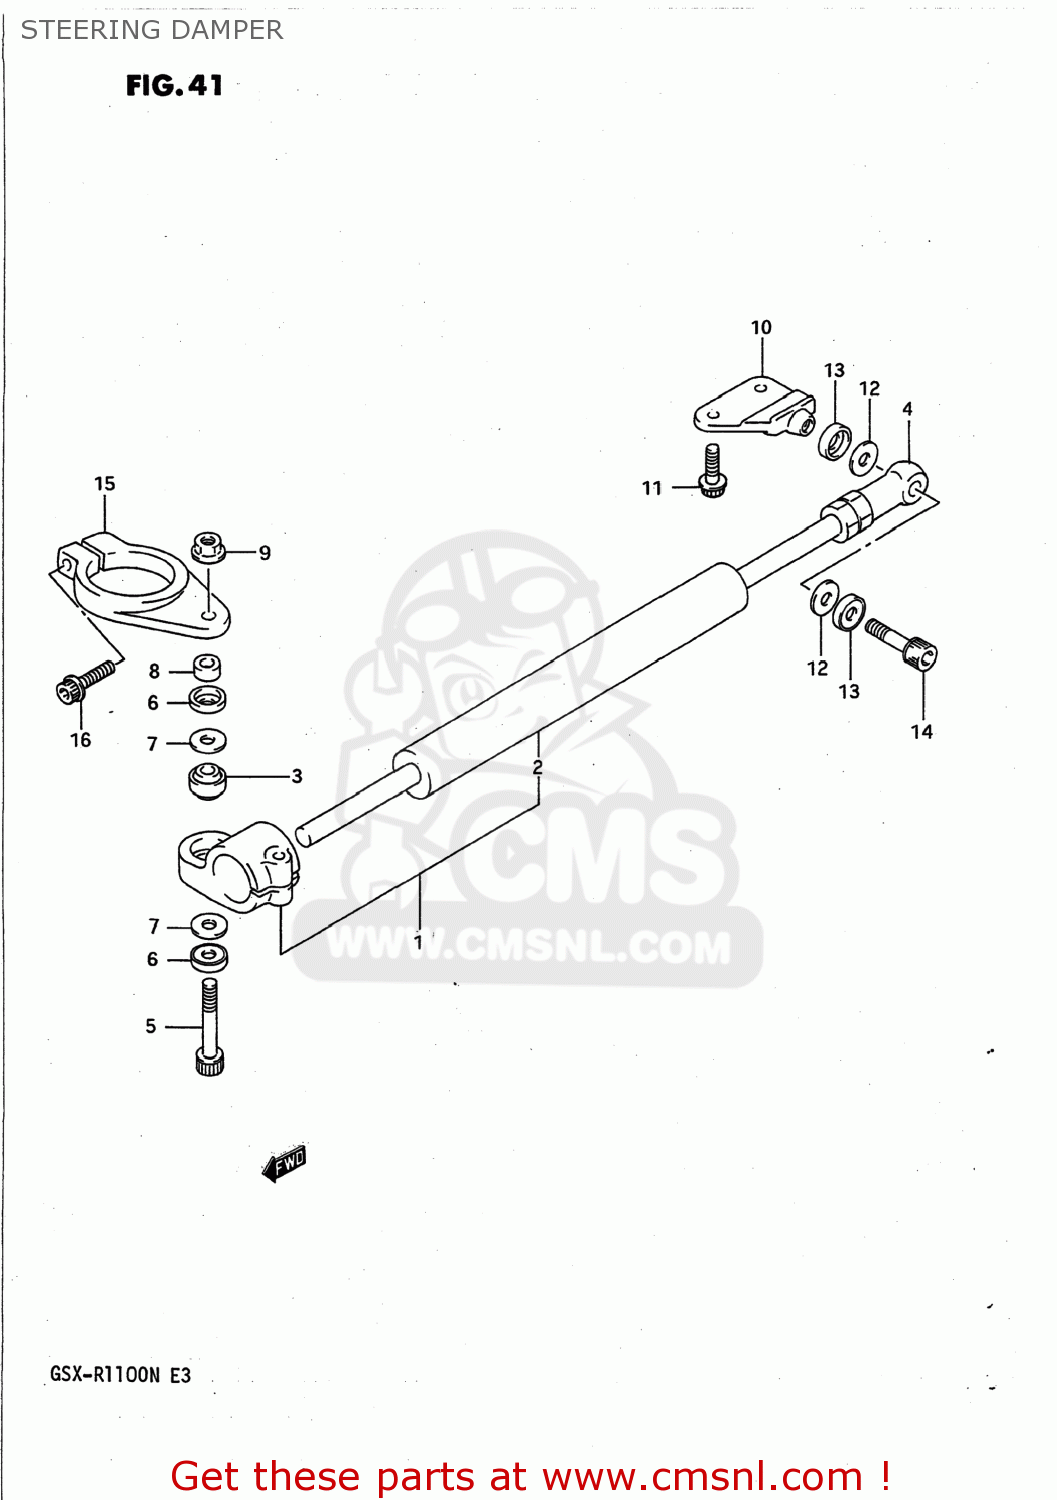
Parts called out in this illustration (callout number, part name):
1	DAMPER ASSEMBLY,STEERING
2	DAMPER,STEERING
3	BEARING(8X17.5X11)
4	PILLOW BALL,ROD END
5	BOLT
6	7
7	SHIM
8	SPACER (8.4X14X6)
9	NUT
10	BOSS,STEERING DAMPER
11	BOLT
12	SHIM
13	14
14	BOLT, FRONT RH
15	BRACKET,STEERING DAMPER
16	BOLT
